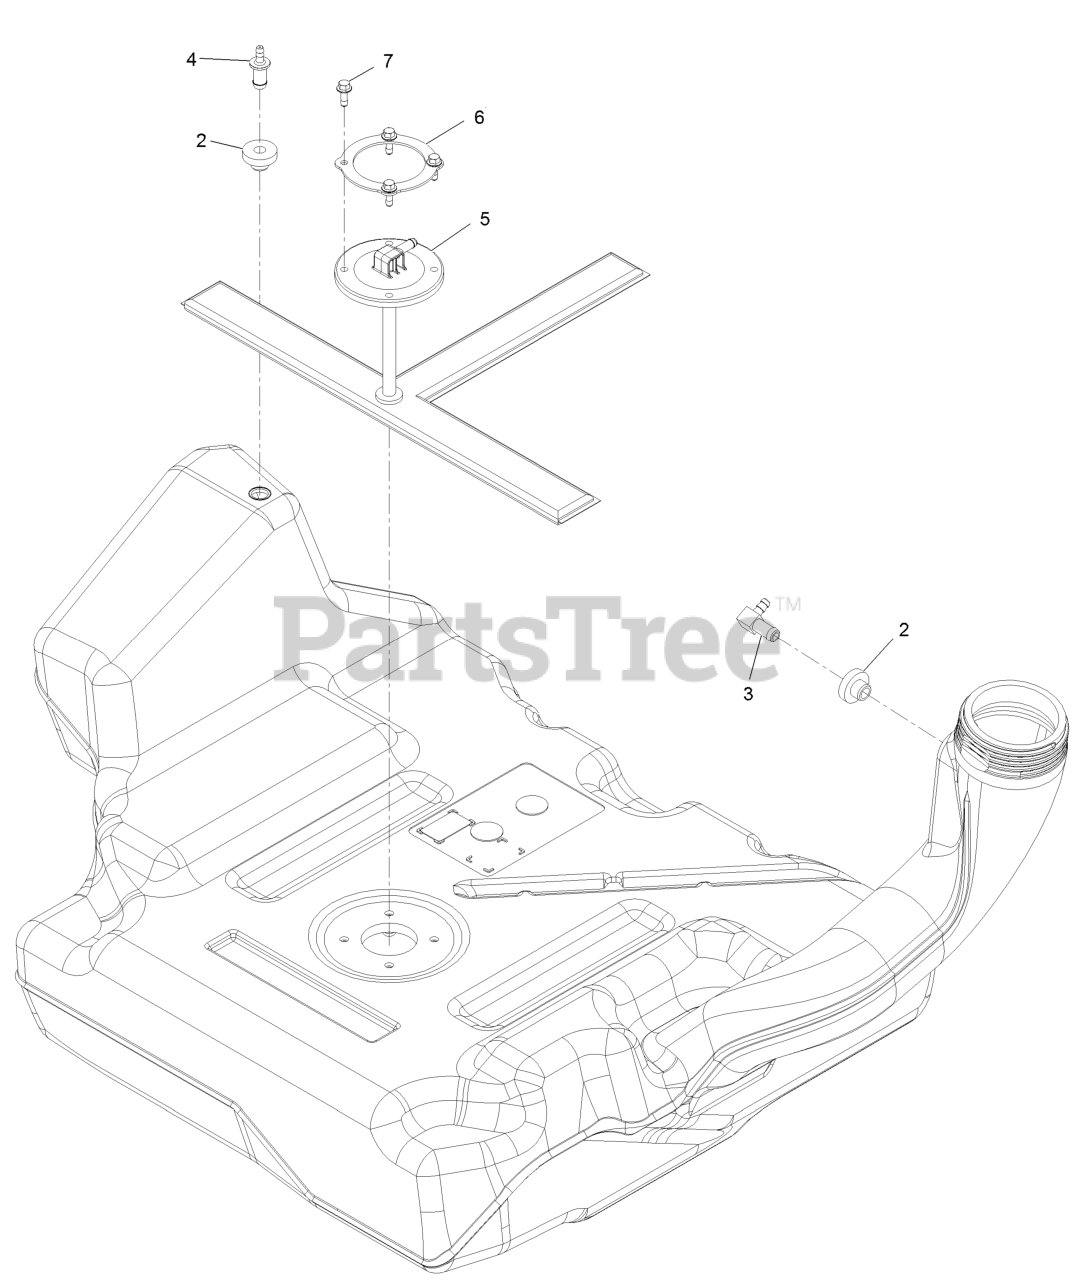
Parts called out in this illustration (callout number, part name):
2	Bushing
3	Fitting-90 DEG
4	Fitting-Orifice, Straight
5	Pickup-Fuel
6	Ring-Retainer
